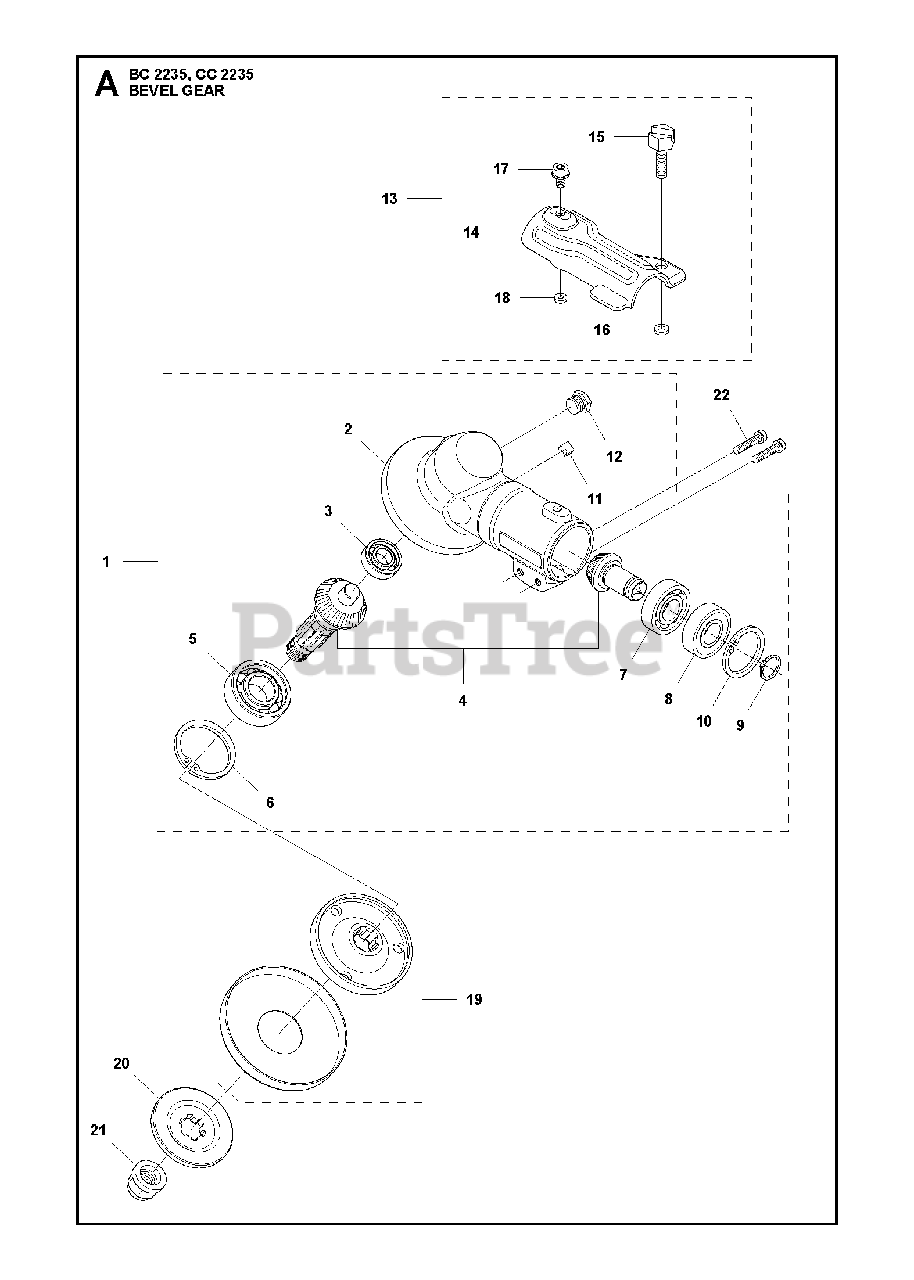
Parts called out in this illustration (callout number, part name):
1	GEAR COMPLETE
2	GEAR CASE
3	BALL BEARING 24X9X1/609ZR
4	SPARE PARTS KIT
5	BALL BEARING
6	RETAINING RING
7	BALL BEARING
8	BALL BEARING
9	SEEGER CLIP
10	RETAINING RING SGH 28
11	MAGNET
12	PLUG
13	CLAMP
14	RP HOLDER
15	SCREW
16	LOCKNUT M6
17	SCREW
18	LOCKING NUT
19	RP CARRIER
20	RP FLANGE
21	NUT BLADE
